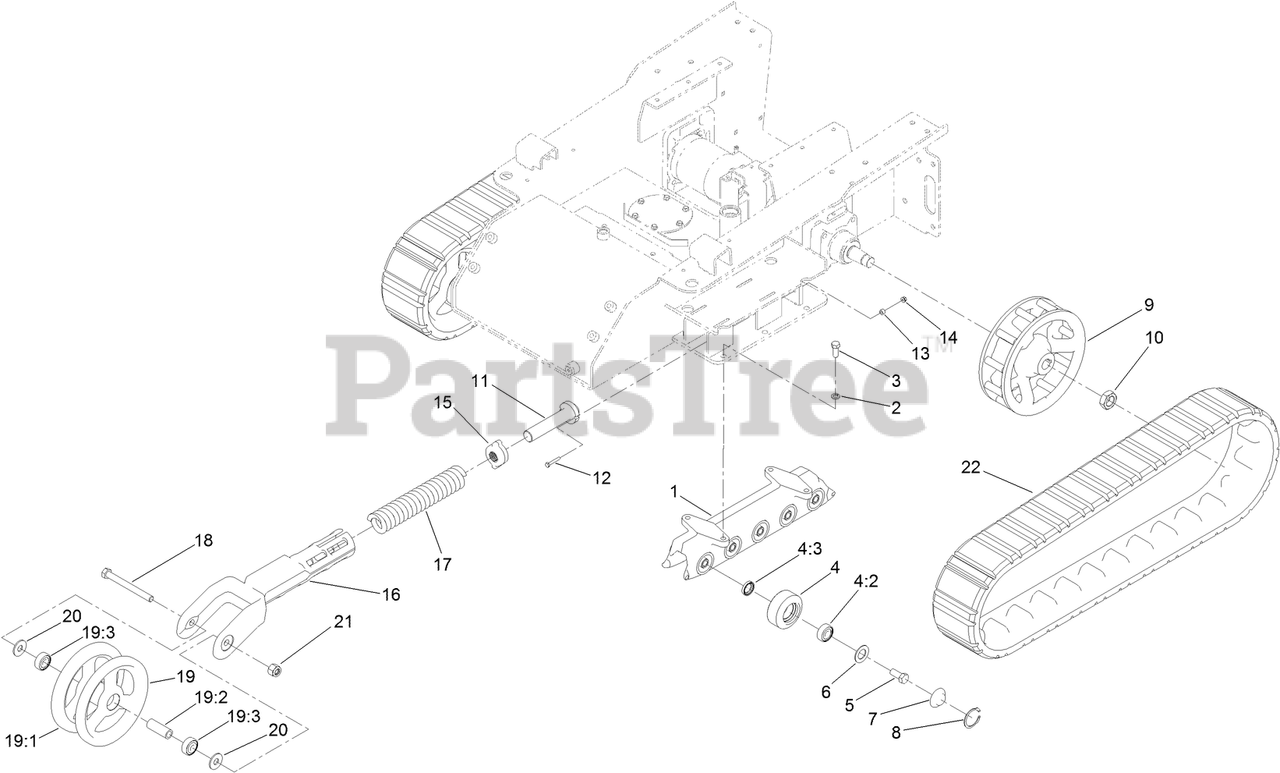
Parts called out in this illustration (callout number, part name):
1	GUIDE-TRACK
2	WASHER-LOCK
3	SCREW-HH
4	ROAD WHEEL ASM
4:2	BEARING-BALL
4:3	SEAL-OIL
5	SCREW-HH
6	GASKET-BOGIE
7	CAP-WHEEL, BEARING
8	RING-SNAP, INTERNAL
9	WHEEL-DRIVE
10	NUT-HEX
11	BOLT-TENSIONER
12	SCREW-HH
13	SPACER
14	NUT-HHF
15	BLOCK-TENSIONER
16	ARM-TENSIONER
17	SPRING-COMPRESSION
18	SCREW-HH
19	TENSIONER WHEEL ASM
19:1	WHEEL-TENSIONER
19:2	SPACER-WHEEL, TENSIONER
19:3	BEARING-BALL
20	WASHER-FLAT
21	NUT-HEX
